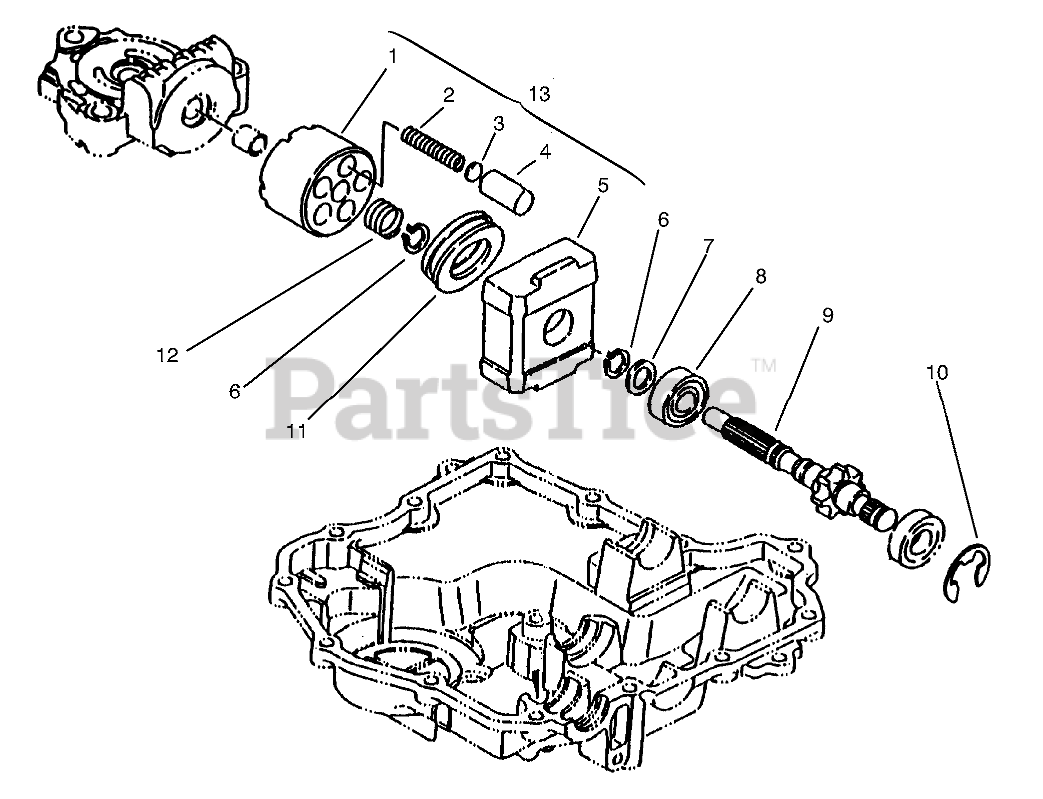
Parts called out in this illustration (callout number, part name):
1	Block-Cylinder
3	Washer
5	HOUSING
6	RING-SNAP
7	WASHER
8	BEARING-BALL
9	SHAFT - MOTOR
10	E-RING
11	BEARING-THRUST
13	ASM - CYCLINDER INC 6-9
